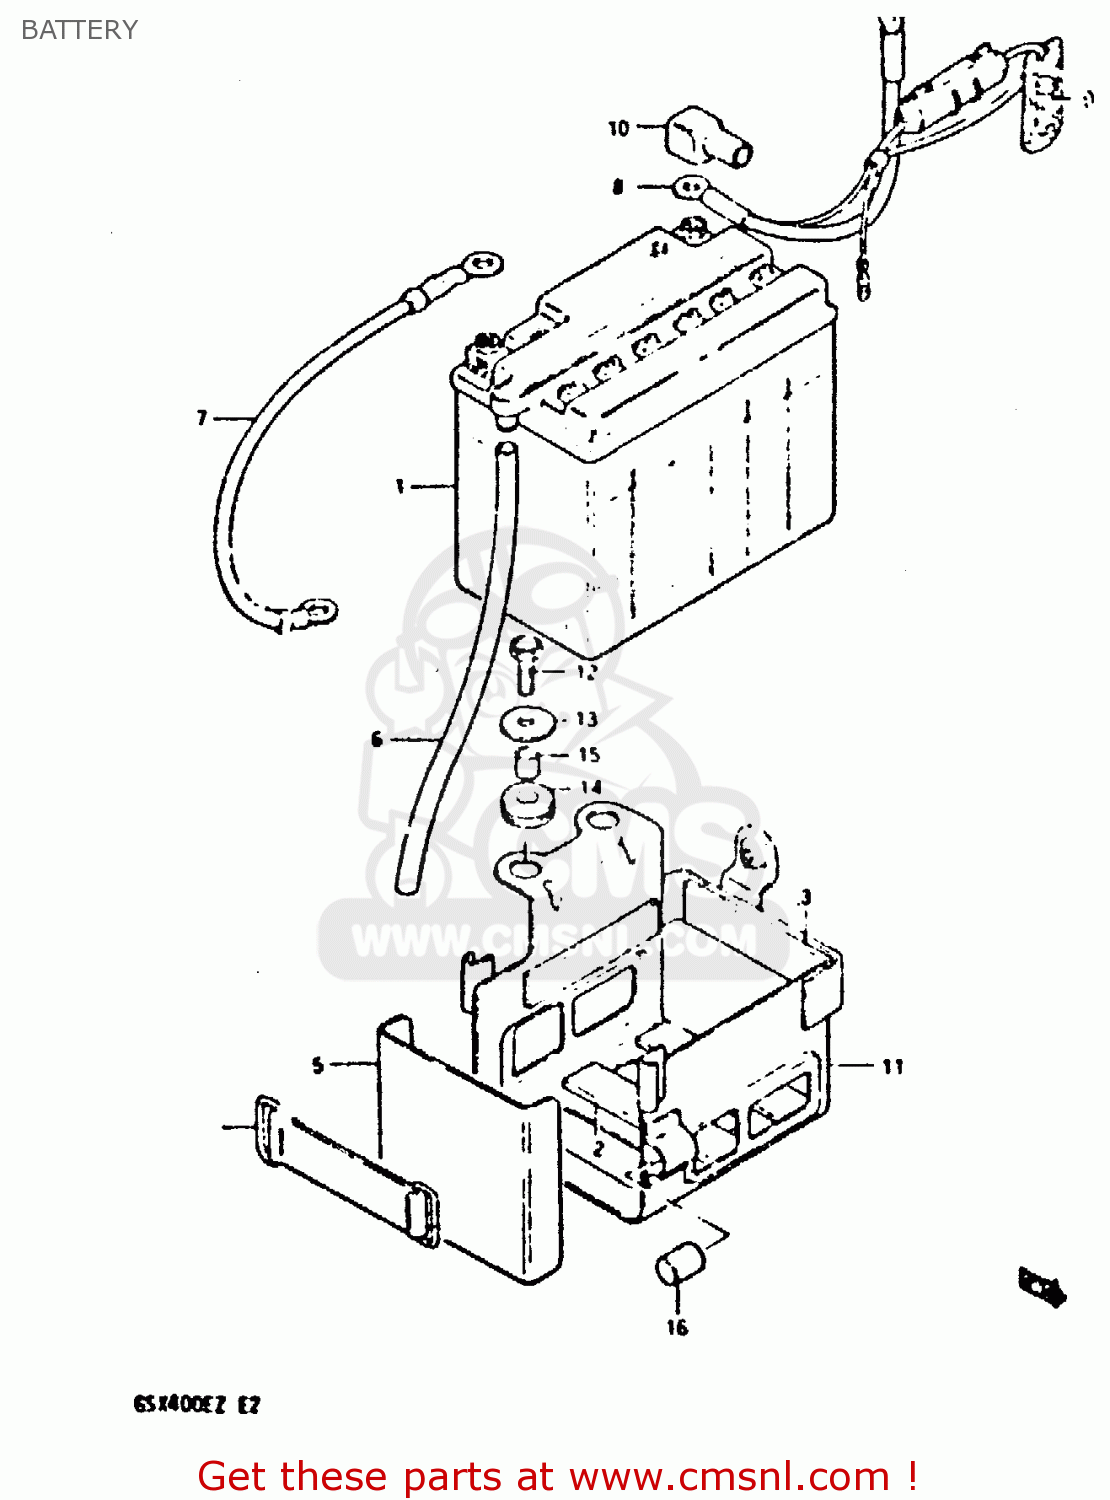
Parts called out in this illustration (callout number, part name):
1	BATTERY(YB12B-B2,12V11.6A)
2	PROTECTOR(20X90)X4
3	PROTECTOR,20X9
4	BAND
5	COVER,BATTERY
6	HOSE,BATTERY EXHAUST
7	LEAD WIRE,BATTERY(-)
8	FUSE CASE AND PLUS CABLE
9	FUSE(15A)
10	CAP,TERMINAL
11	HOLDER,BATTERY
12	BOLT
13	WASHER
14	CUSHION
15	SPACER (6.1X9X9)
16	CUSHION
